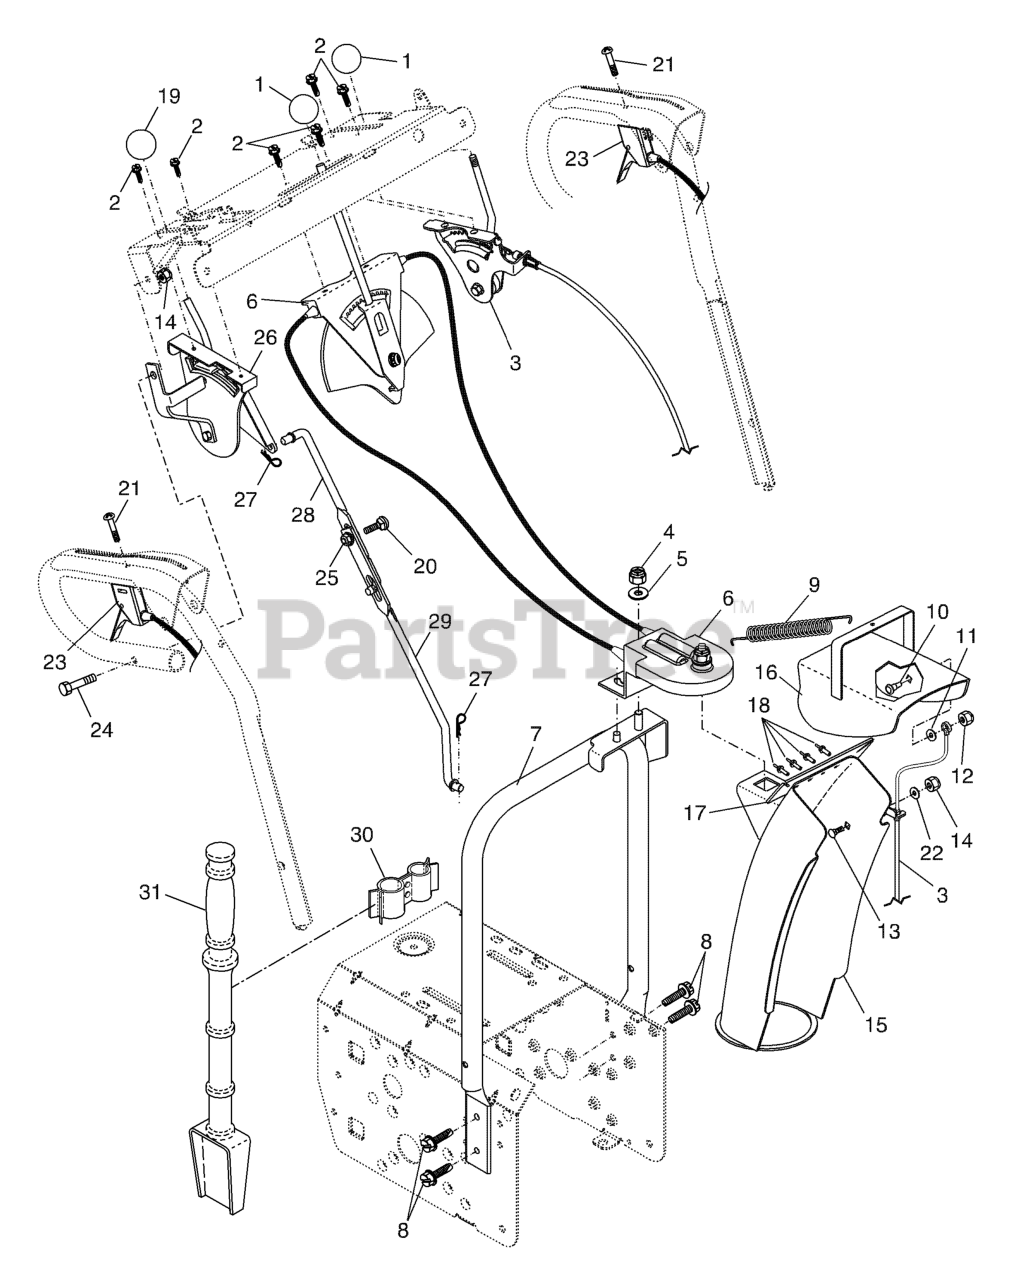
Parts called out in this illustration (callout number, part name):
1	KNOB, LEVER
2	SCREW #10-24 X 5/8
3	CONTROL ASSY, DEFLECTOR
4	NUT
5	WASHER
6	CONTROL ASSY, CHUTE ROTATER
7	SUPPORT CHUTE ROTATER
8	SELF-TAPPING SCREW 5/16-18X3/4
9	SPRING.DEFLECTOR.REM.CHUTE
10	BOLT, SHOULDER
11	WASHER, NYLON FRICTION
12	LOCKNUT.NYLOC.1/4-20
13	BOLT
14	NUT.71038.31-18.HEX.NYLOCK
15	CHUTE ASSY
16	DEFLECTOR.WELDMENT.PNT.ORANGE
17	SEAL, DEFLECTOR
18	RIVET BLIND
19	RP KNOB, SPEED CONTROL LEVER
20	BOLT
22	WASHER.20X8.5
23	STEERING.CONTROL.SNOW.BLUE
25	NUT.FLANGE.5/16
26	LEVER ASSEMBLY, SPEED CONTROL
27	SPRING RETAINER
28	ROD, UPPER SPEED CONTROL
29	ROD, LOWER SPEED CONTROL.SNOW
30	CLAMP.ASM.CLEANOUT.TOOL.SNOW
31	CLEAN OUT TOOL
